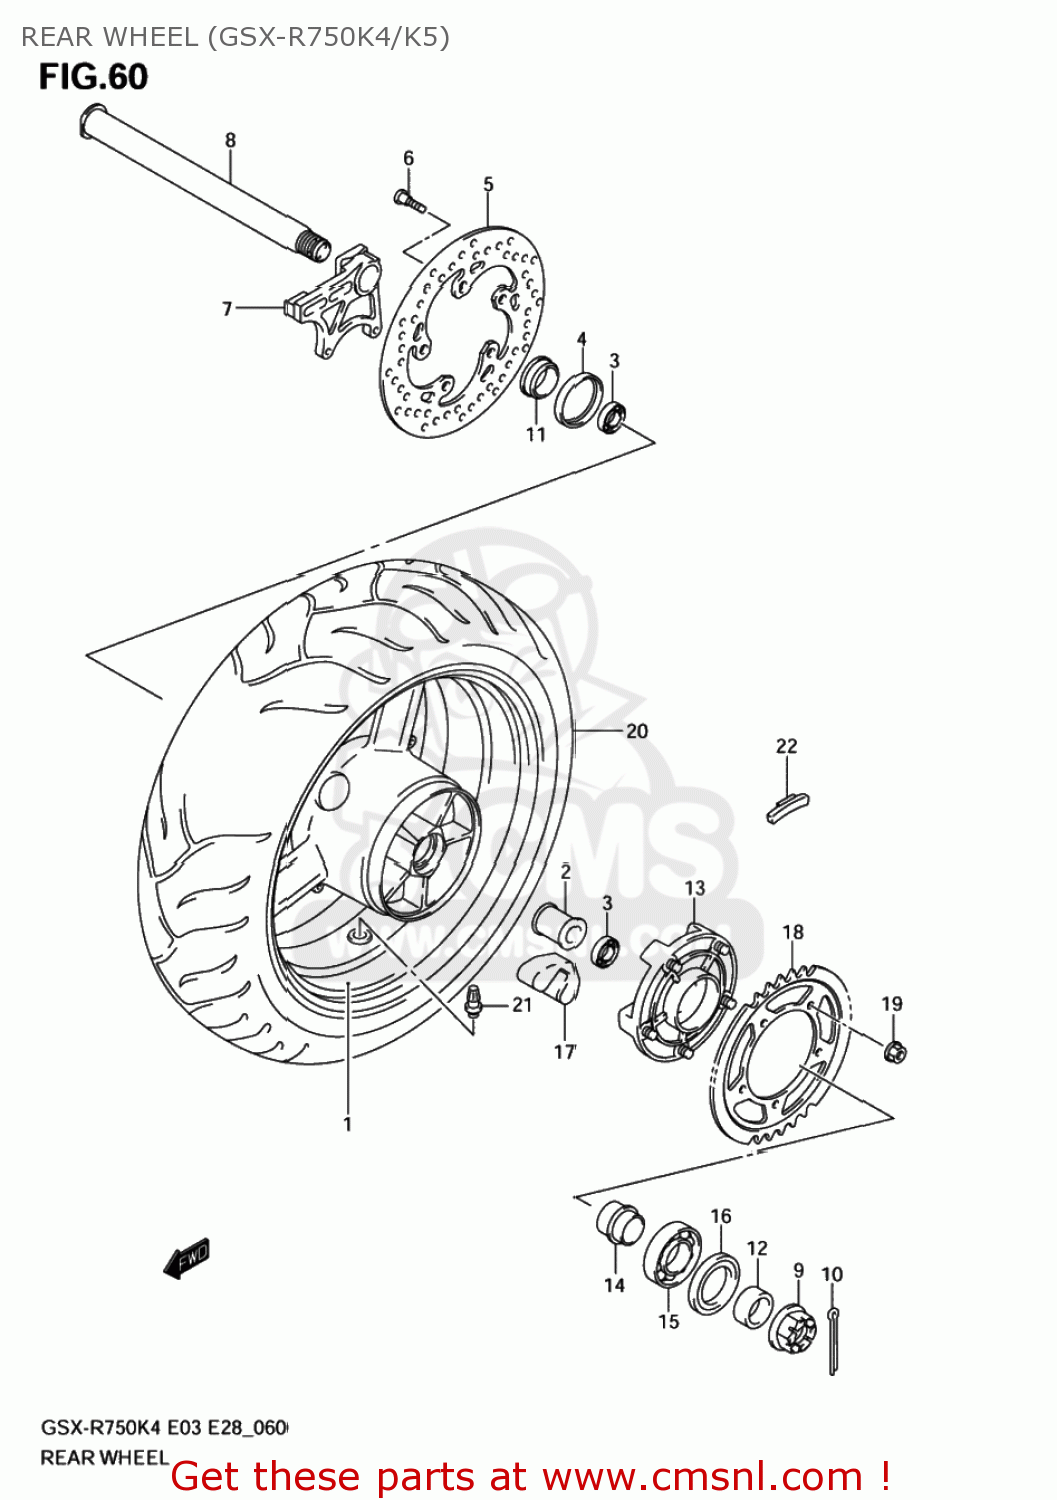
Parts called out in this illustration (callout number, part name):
1	WHEEL,RR(17M/CXMT5.50)
2	SPACER,RR HUB BEARING
3	BEARING(28X52X12)
4	SEAL,OIL(37X52X8)
5	DISC,RR BRAKE
6	BOLT(8X33)
7	BRACKET,RR CALIPER
8	AXLE,RR
9	NUT
10	PIN, COTTER
11	SPACER,RR AXLE,R
12	SPACER,RR AXLE,L
13	DRUM,RR SPROCKET
14	RETAINER,RR SPROCKET DRUM
15	BEARING
16	SEAL,OIL(39X65X7)
17	ABSORBER,RR HUB SHOCK
18	SPROCKET,RR(43T-525)
19	NUT
20	TIRE, REAR,180/55 ZR17M/C
21	VALVE ASSY,WHEEL RIM(TR412)
22	WEIGHT,WHEEL BALANCE 10G
